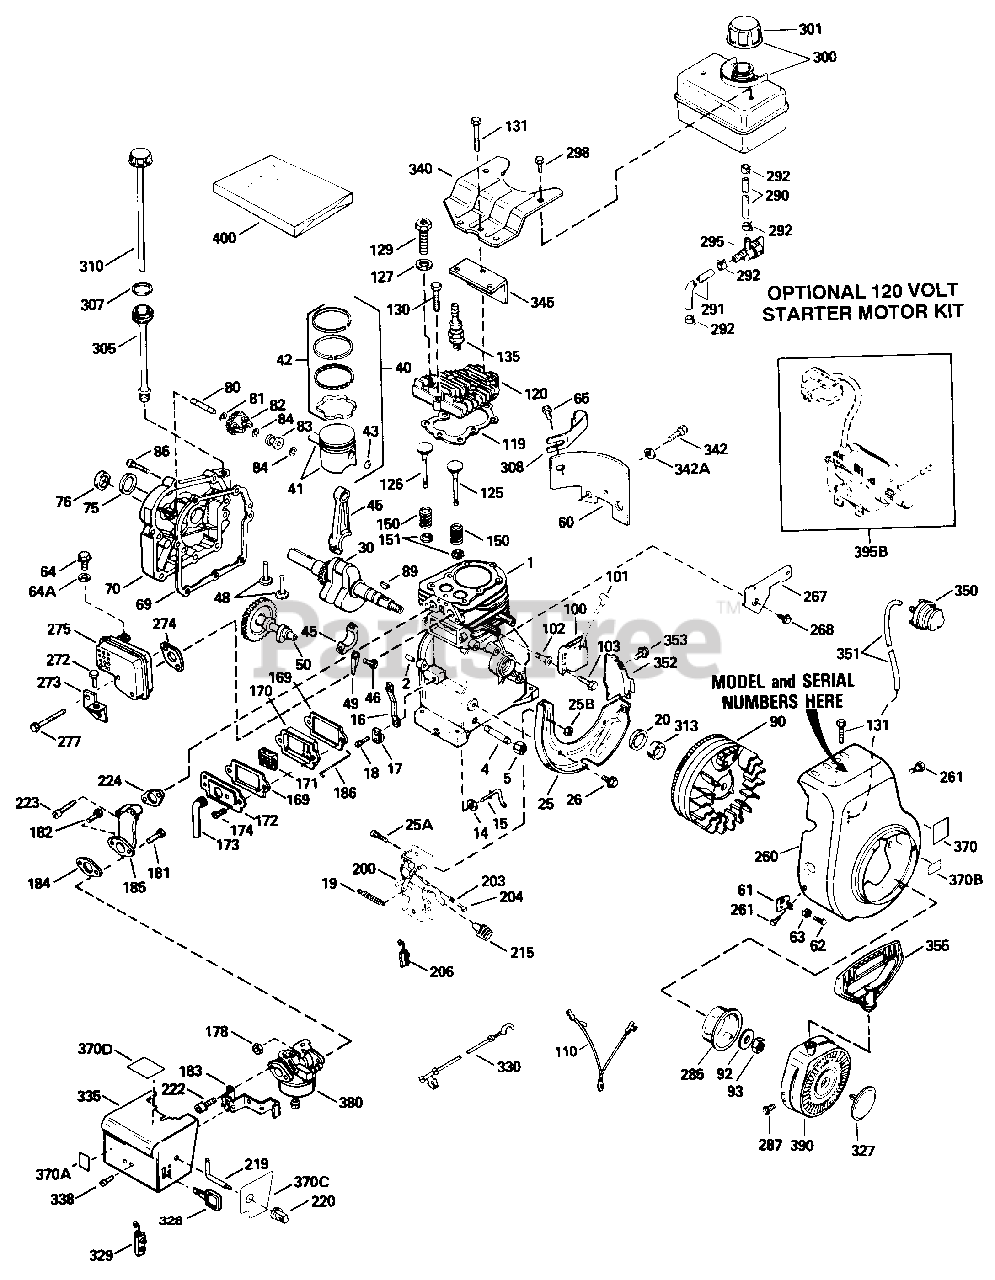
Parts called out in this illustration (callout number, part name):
1	Cylinder Ass'y.
2	Pin, Dowel
4	Nipple, Pipe
5	Cap, Oil Drain
14	Washer, Flat
15	Rod, Governor
16	Lever, Governor
17	Clamp, Governor Lever
18	Screw, Hex Washer Hd., 8-32 x 5/16
19	Spring, Extension
20	Seal, Oil
25	Baffle, Lower Housing
25A	Screw, Fil. Hd. Sems, 8-32 x 1/2
25B	Nut, Lock, 8-32
26	Screw, Hex Washer Hd. Durlok, 1/4-20 x 5/8
30	Crankshaft Ass'y.
40	Piston, Pin & Ring Ass'y. (Std.)
41	Piston & Pin Ass'y. (Std.)
42	Ring Set, Piston (Std.)
42	Ring Set, Piston (.010 Oversize)
42	Ring Set, Piston (.020 Oversize)
43	Ring, Piston Pin Retaining
45	Rod Ass'y., Connecting
46	Bolt, Connecting Rod
48	Lifter, Valve
49	Dipper, Oil
50	Camshaft (Compression Release)
60	Extension, Blower Housing
61	Bracket, Grommet Mounting
62	Screw, Pan Hd. Taptite, 8-32 x 3/8
63	Grommet, Plastic
64	Screw, Torx T-30 Hex Washer Hd. Sems, 1/4-20 x 1/2
64A	Washer, Flat
65	Screw, Hex Hd. Sems, 10-24 x 1/2
69	Gasket, Cylinder Cover
70	Cover, Cylinder
75	Seal, Oil
76	Seal, Camshaft
80	Shaft, Mechanical Governor
81	Washer, Flat
82	Gear, Governor
83	Spool, Governor
84	Ring, Retaining
86	Screw, Hex Hd. Sems, 1/4-20 x 1-1/4
89	Key, Flywheel
90	Flywheel (w/Ring Gear)
92	Washer, Belleville
93	Nut, Flywheel
100	Solid State Ass'y.
101	Cover, Spark Plug
102	Stud, Solid State Mounting
103	Screw, Torx T-15 Hex Washer Hd. Sems, 10-24 x 1
110	Wire, Ground
119	Gasket, Cylinder Head
120	Head, Cylinder
125	Valve, Exhaust (Std.)
125	Valve, Exhaust (1/32" Oversize)
126	Valve, Intake (Std.)
126	Valve, Intake (1/32" Oversize)
127	Washer, Flat
129	Screw, Special Hex Hd., 5/16-18 x 1-1/2
130	Screw, Hex Flange Hd., 5/16-18 x 1-1/2
131	Screw, Hex Flange Hd., 5/16-18 x 2
135	Spark Plug, Resistor
150	Spring, Valve
151	Cap, Valve Spring
169	Gasket, Valve Cover
170	Body, Valve Cover
171	Element, Valve Body
172	Cover, Breather
173	Tube, Breather
174	Screw, Hex Hd. Sems, 10-24 x 1/2
178	Nut & Lock Washer, 1/4-28
181	Screw, Hex Hd., 1/4-28 x 7/8
182	Screw, Hex Hd., 1/4-28 x 1-11/16
183	Bracket, Choke
184	Gasket, Carburetor
185	Pipe, Intake
186	Link, Governor to Throttle
200	Control Ass'y., Bracket
203	Spring, Compression
204	Screw, Fil. Hd., 5-40 x 7/16
206	Terminal Ass'y.
215	Knob, Speed Control
219	Rod, Choke
220	Knob, Choke Control
222	Screw, Fil. Hd. Sems, 10-32 x 1/2
223	Screw, Fil. Hd. Sems, 1/4-20 x 1-19/32
224	Gasket, Intake
260	Housing, Blower
261	Screw, Hex Hd. Sems, 1/4-28 x 7/16
267	Bracket, Hold Down
268	Screw, Hex Washer Hd. Self-Tap Sems 10-24 x 9/16
272	Screw, Hex Hd. Sems, Taptite, 10-24 x 3/8
273	Bracket, Carburetor Cover
274	Gasket, Exhaust
275	Muffler
277	Screw, Fil. Hd. Sems, 1/4-20 x 2-1/2
285	Cup, Starter
287	Screw, Hex Washer Hd., 8-32 x 1/2
290	Line, Fuel
291	Line, Fuel
292	Clamp, Fuel Line
295	Valve, Shut-Off
298	Screw, Hex Washer Hd. Self-Tap Sems, 1/4-15 x 7/8
300	Tank Ass'y., Fuel
301	Cap, Fuel Tank
305	Tube Ass'y., Oil Fill
308	Clip, Oil Fill
313	Spacer, Flywheel Key
327	Plug, Starter
328	Key, Ignition
329	Terminal Ass'y.
330	Wire, Ground
335	Cover, Carburetor
338	Screw, Pan Hd. Sems, 8-32 x 5/16
340	Plate, Fuel Tank
342	Screw, Hex Hd. w/Belleville Washer, 1/4-20 x 1/2
342A	Washer, Flat
345	Baffle, Heat
350	Primer Ass'y.
351	Line, Primer
352	Extension, Baffle
353	Screw, Hex Wash. Hd., 8-32 x 1/2
355	Handle, Starter
370	Decal (5.0 H.P.)
370A	Decal, Instruction
370B	Decal, Primer
370C	Decal, Choke
370D	Decal, Warning
380	Carburetor
390	Starter, Rewind
395B	Electric Starter Kit
400	Gasket Set
